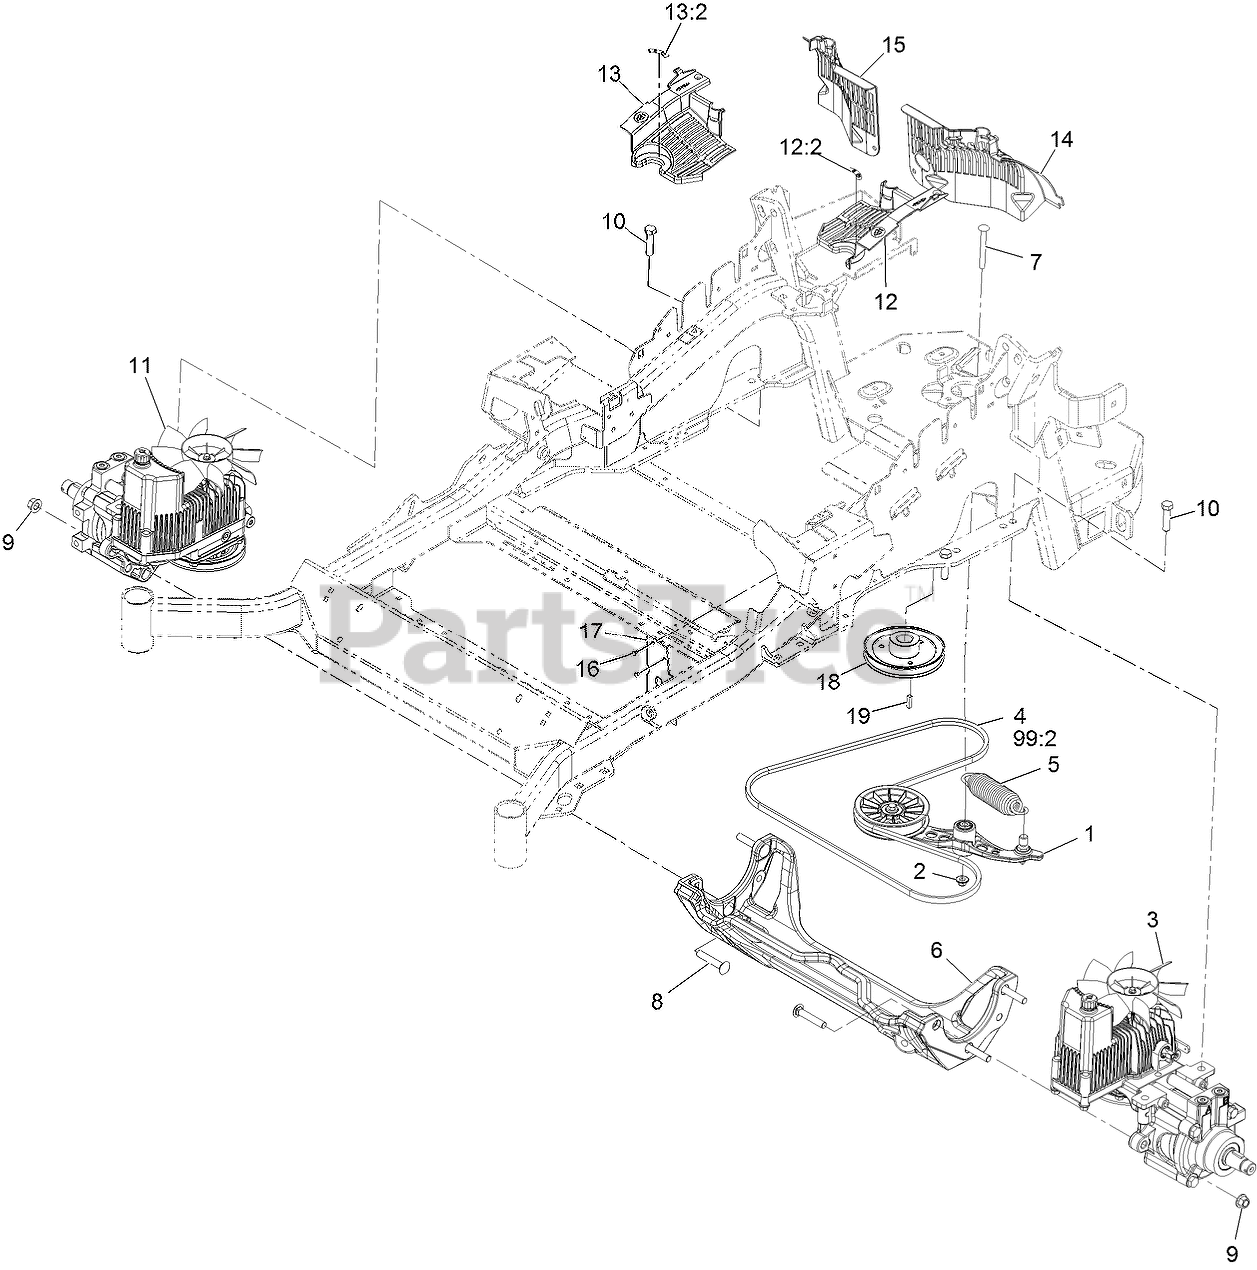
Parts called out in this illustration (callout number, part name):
1	PUMP IDLER ASM
2	Nut-Nyloc 3/8-16 Flg
3	LH HYDRO ASM (12CC W/ SHO
5	SPRING-EXTENSION
6	CRADLE-HYDRO
7	BOLT-SHOULDER, CARRIAGE 3/8-16 X 3 1/2
8	SCREW-CARR
9	Nut-Lock 1/2-13
10	SCREW-HH
11	RH HYDRO ASM (12CC W/ SHO
12	LH HYDRO GUARD ASM
12:2	DECAL-OIL, HYDRO
13	RH HYDRO GUARD ASM
13:2	DECAL-OIL, HYDRO
14	GUARD-HYDRO, REAR (LH)
15	GUARD-HYDRO, REAR (RH)
16	RIVET-POP
17	DEFLECTOR-AIR FLOW
18	SHEAVE
99:2	BELT
